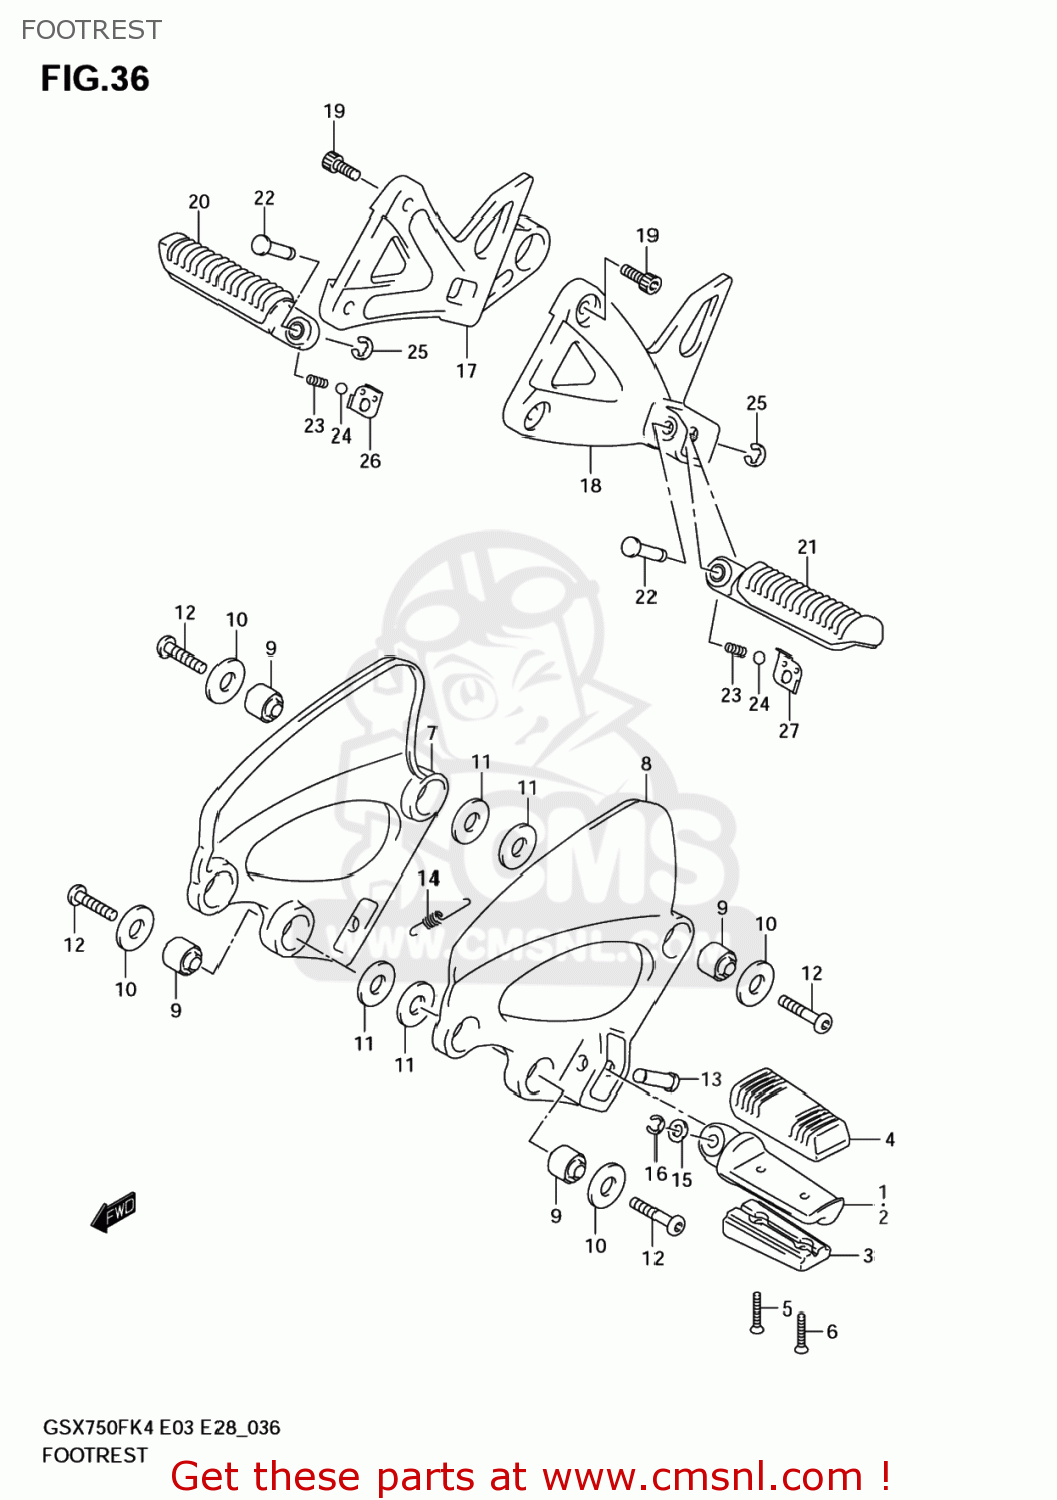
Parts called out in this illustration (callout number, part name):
1	BAR,FR FOOTREST,R
2	BAR,FR FOOTREST,L
3	BAR,FR FOOTREST NO.2
4	RUBBER,FR FOOTREST
5	SCREW, INNER
6	SCREW
7	HOLDER,FR FOOTREST,R
8	HOLDER,FR FOOTREST,L
9	BUSH(8.4X20X16)
10	WASHER(13.7X24X2)
11	WASHER(17.2X24X2.2)
12	BOLT(8X30)
13	PIN(8X33.2)
14	SPRING
15	WASHER
16	E.RING
17	BRACKET,PILLION FOOTREST,R
18	BRACKET,PILLION FOOTREST,L
19	BOLT(8X23)
20	BAR,PILLION FOOTREST,R
21	BAR,PILLION FOOTREST,L
22	PIN
23	SPRING
24	BALL
25	E.RING
26	PLATE,PILLION FOOTREST,R
27	PLATE,PILLION FOOTREST,L
